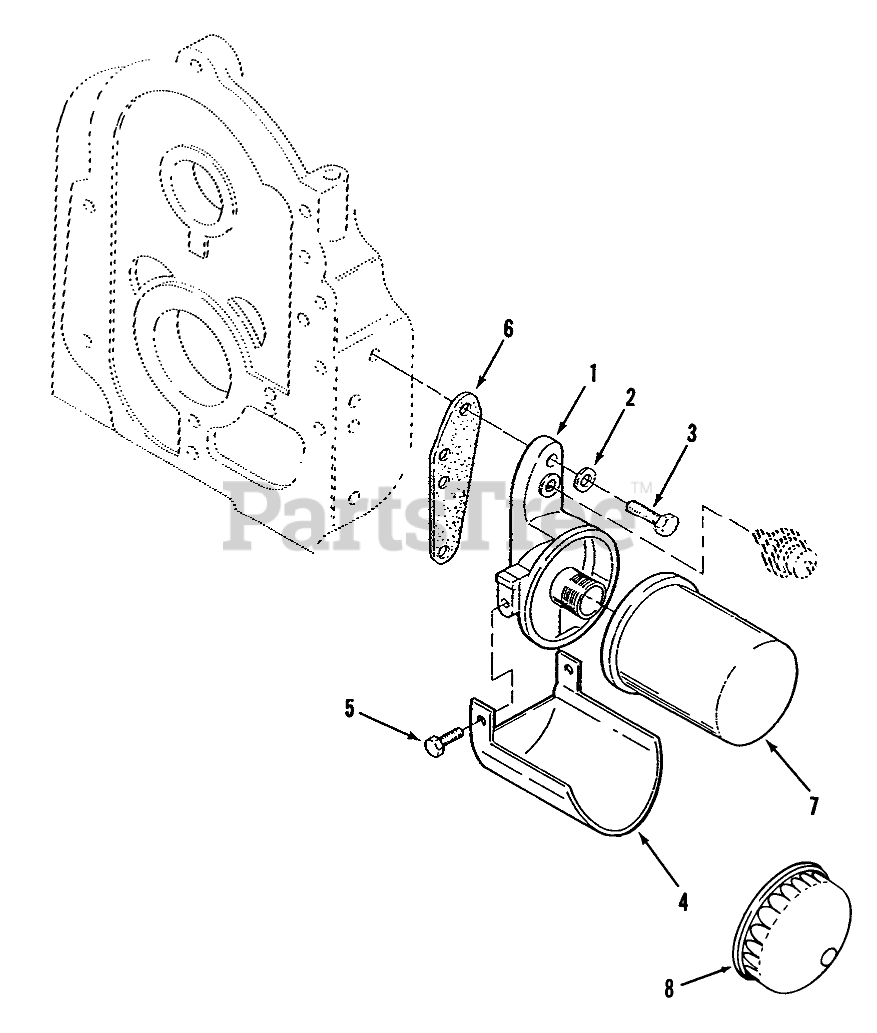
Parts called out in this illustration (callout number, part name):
1	Adapter
2	Washer
3	HHCS 5/16-18 X 1
4	Oil Filter Drain
5	Bolt
6	Oil Filter Adapter Gasket
7	Oil Filter
8	Oil Filter Wrench
